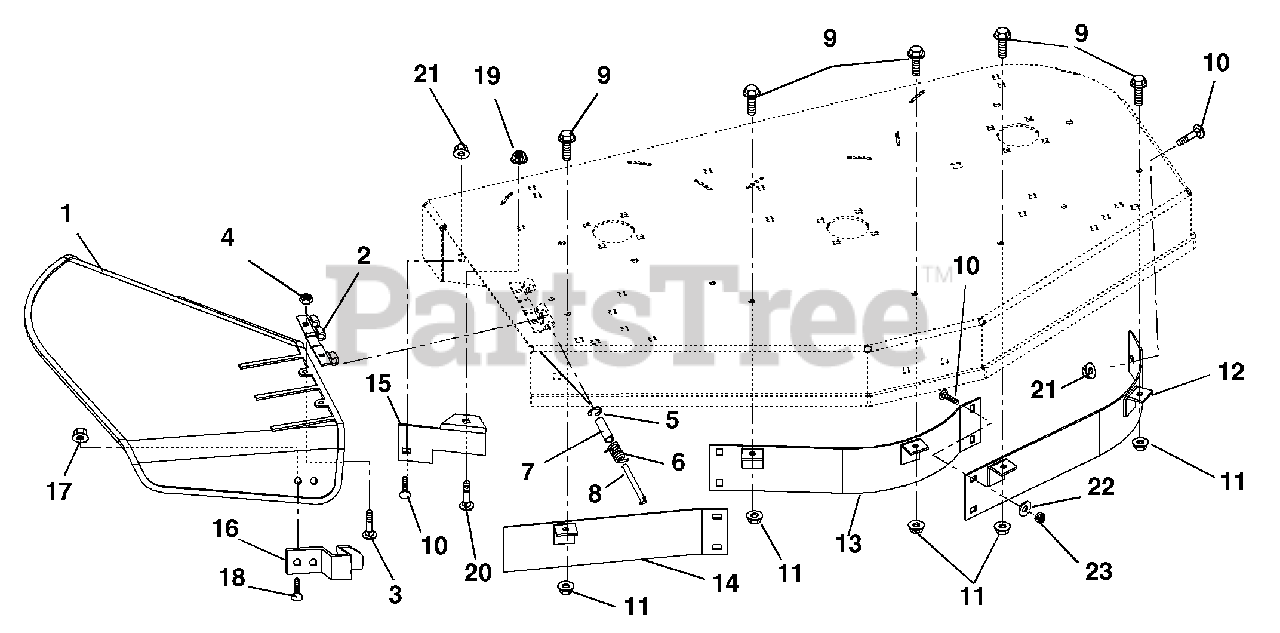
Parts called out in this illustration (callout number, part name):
1	DEFLECTOR, CHUTE
2	HINGE PLATE
3	@BLT-RDHDSQNK .25-20X.75 GR5BZ
4	NUT-SPNLK-FLG .250-20 BKZC
5	RG-RTNG-EXT .312X.025
6	SG-TORS .095X.50X 1.0
7	BSHG-SLV .334 X .502 X 1.437
9	BLT SERHFWH .31-18X.62 GR5BKZC
10	BLT-RDHDSQSHNK .31-18X.62 BKZC
11	NUT-LK-TOP-FLG .31-18 BLKZC
12	BAFFLE - LEFT FRONT - 40"
13	BAFFLE - CENTER FRONT - 40"
14	BAFFLE - RIGHT FRONT - 40"
15	DEFLECTOR-40"
16	FLAT SPRING
17	NUT-LK-TOP-FLG .25-20 BKZC
18	@BLT-RDHDSQNK .25-20X.50 GR5BZ
19	NUT-LK-TOP-FLG .38-16 BLKZC
20	BLT-RDHDSQNK .38-16X.75 G5BZ
21	NUT-5/16-18 FLG NYLOC BK ZN
22	@WSHR-FL-STL.344X.688X.065YWZC
23	@NUT-LK-NYL .312-18 YWZC
